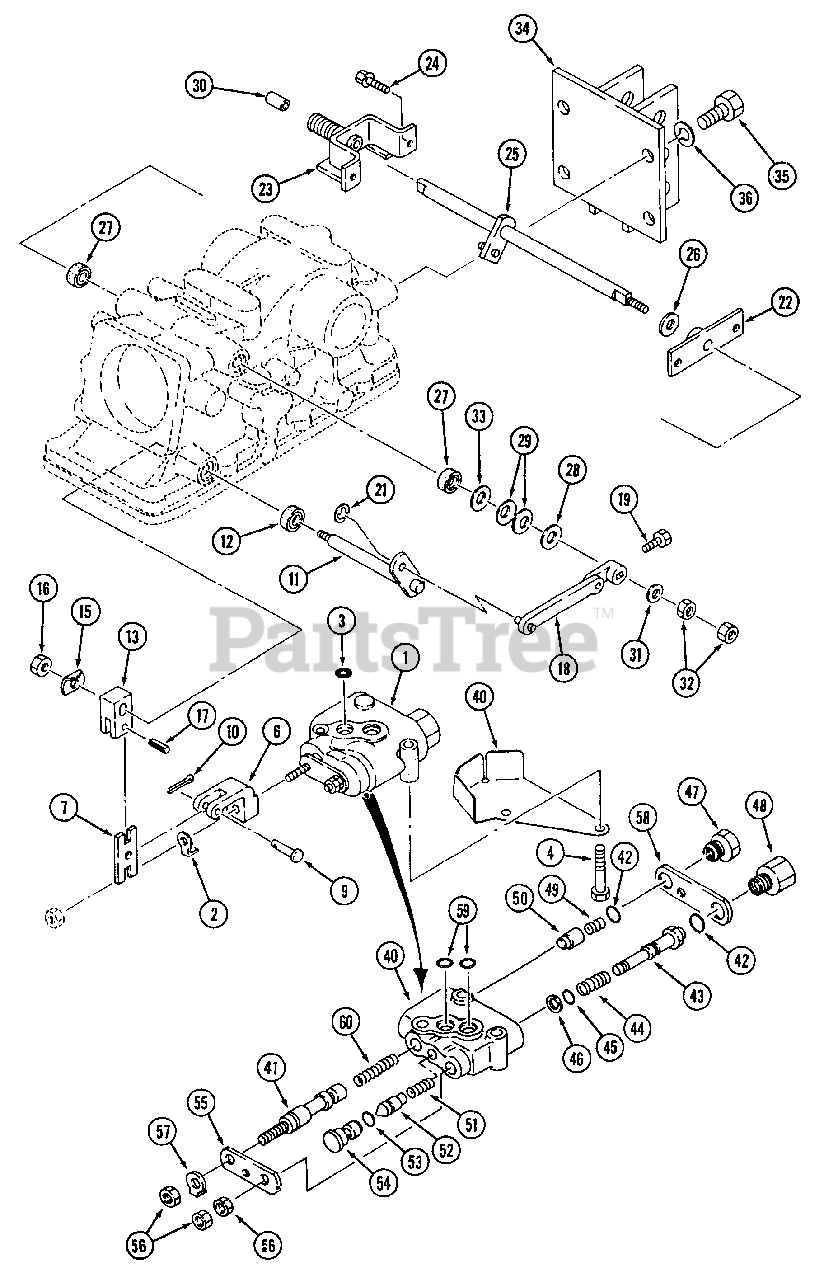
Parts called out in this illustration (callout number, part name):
1	Valve, Control
2	Plate, Stopper
10	Pin, Split
13	Shifter, Valve
26	Lining, Brake
28	Washer
33	Washer
34	Bracket, Top Link
40	Body Ass'y.
41	Spool
46	Ring, Back Up
49	Spring
50	Valve, Unloader
57	Plate, Stopper
60	Spring, Return
